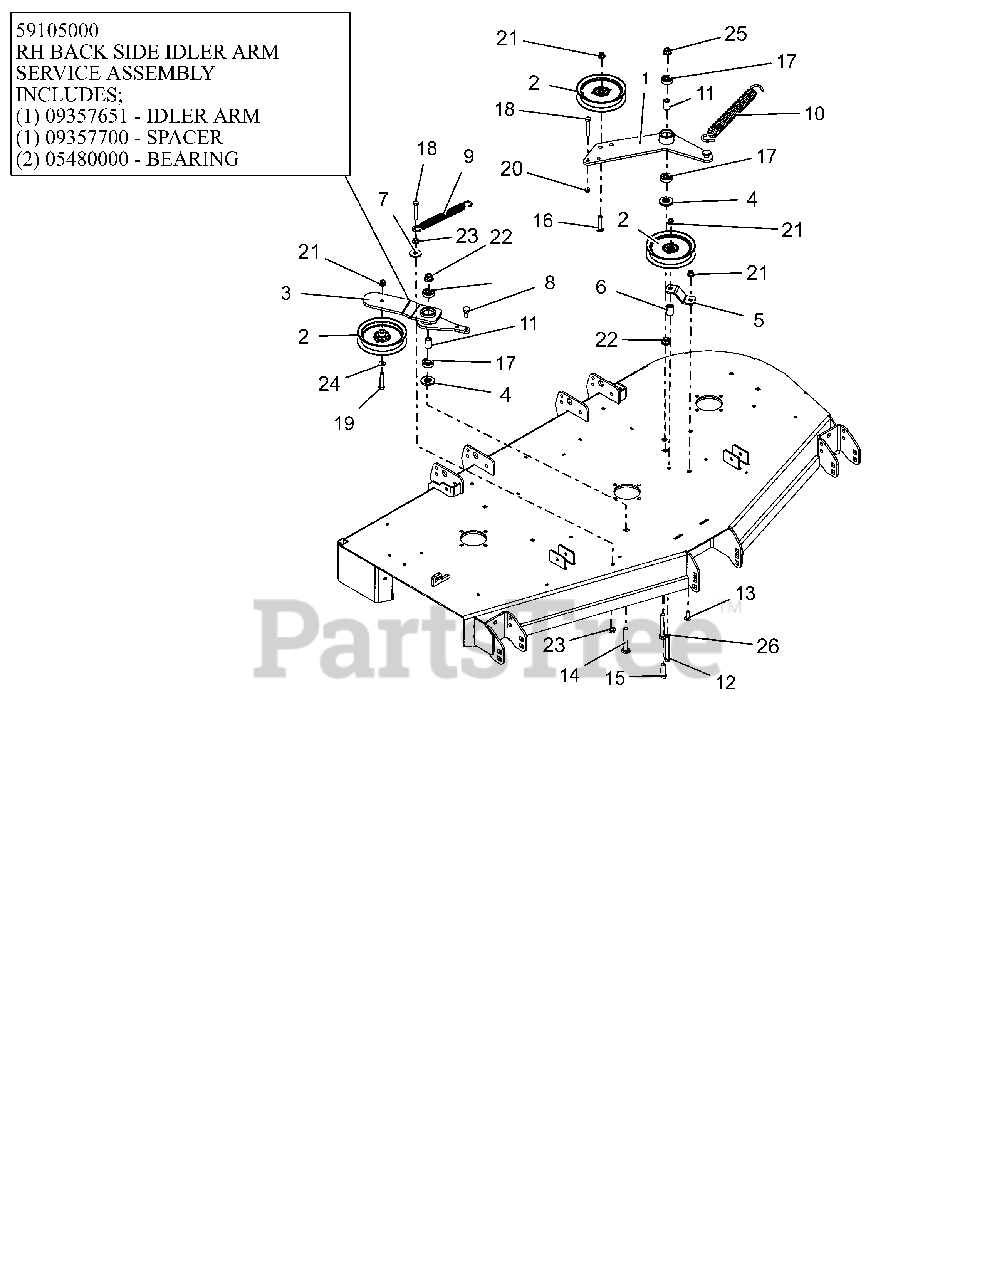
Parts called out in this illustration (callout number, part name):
1	DECK PTO IDLER ARM WLDMT - BLK
2	IDLER, FLAT 5.00"
3	DECK RH IDLER ARM WMT - BLK
3	RH BACKSIDE IDLER ARM ASSEMBLY
4	SPACER, IDLER ARM
5	PTO FIXED IDLER MTG BRKT -RED
6	BUSHING, SLV .380X.750X1.190
7	WSHR-FL-STL .406X1.375X.135 YZ
8	BLT,SHLDR EP .38-16X.30 HEX YZ
9	SPRING, EXTENSION
10	SPRING, EXTENSION
11	SPACER .510 X .75 X 1.1485
12	@BLT-HEX .38-16X3.25 GR5 YWZC
13	@BLT-RDHDSHSQNK.38-16X1.0 G5YZ
14	BLT,RDHDSQSHNK.50-13X3.25 G5YZ
15	@BLT-HEX .50-13X1.50 GR5 YWZC
16	BLT-RDHDSQNK .38-16X2.00 SHTYW
17	BRG-BALL .500X1.38X.437
18	@BLT-HEX .38-16X2.25 GR5 YWZC
19	@BLT-HEX .38-16X2.00 GR5 YWZC
20	NUT-HEX-JAM .375-16 YWZC
21	@NUT-LK-NYL-FLG .38-16 YWZC
22	@NUT-LK-NYL-FLG .50-13 YWZC
23	@NUT-SPNLK-FLG .375-16 YWZC
24	@WSHR-FL-STL.406X.812X.065 YWZ
25	NUT-LK-CTR-FLG .50-13 YWZC
26	@BLT-HEX .50-13X3.00 GR5 YWZC
